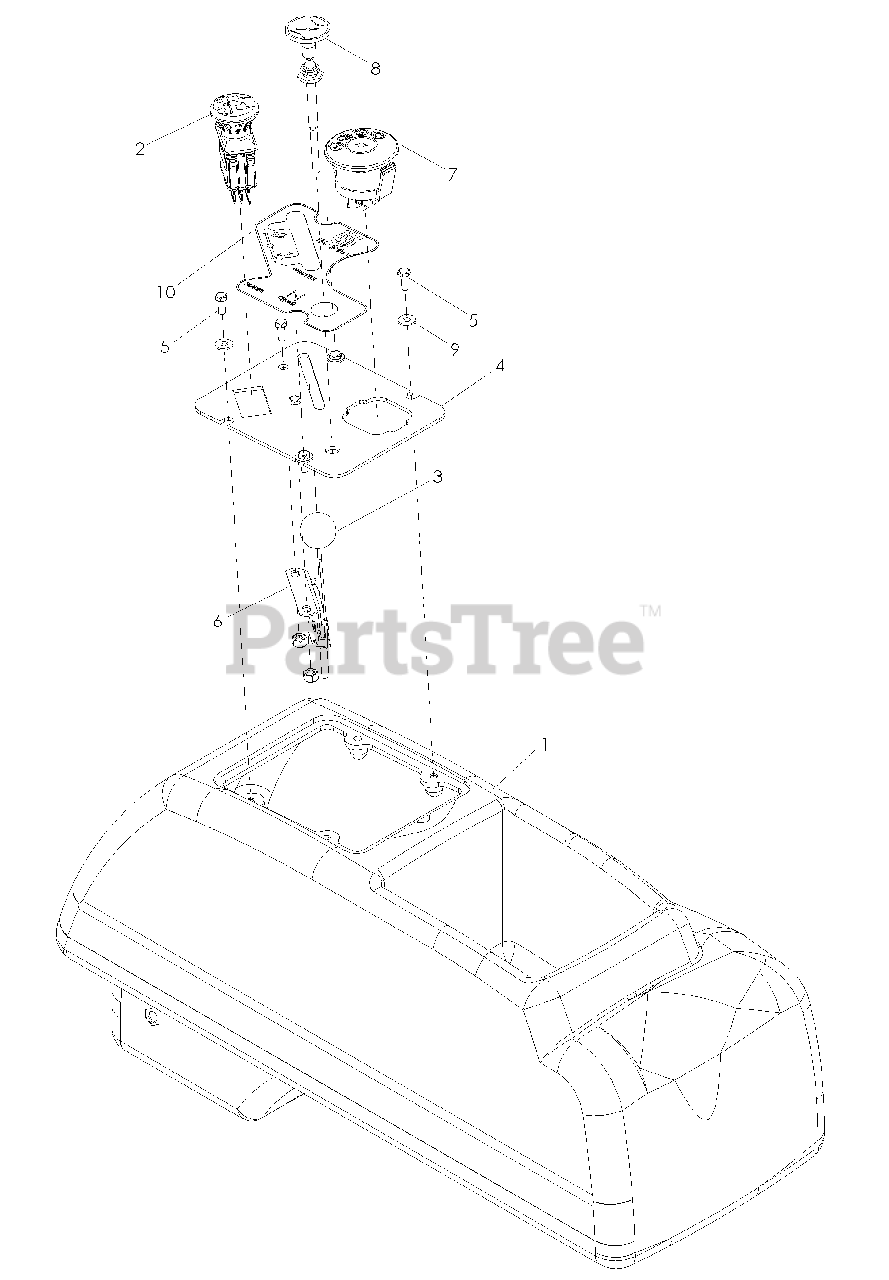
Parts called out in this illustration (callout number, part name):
2	SWITCH, PTO 10 AMP
3	THROTTLE CABLE
4	CONSOLE PLATE
5	SCREW #10-24 x 1/2 SLT HEX
6	NUT #10-24 HEX NYLOC
7	IGNITION SWITCH
8	CONTROL, CHOKE
9	WASHER #10 FLAT
10	DECAL, CONSOLE
